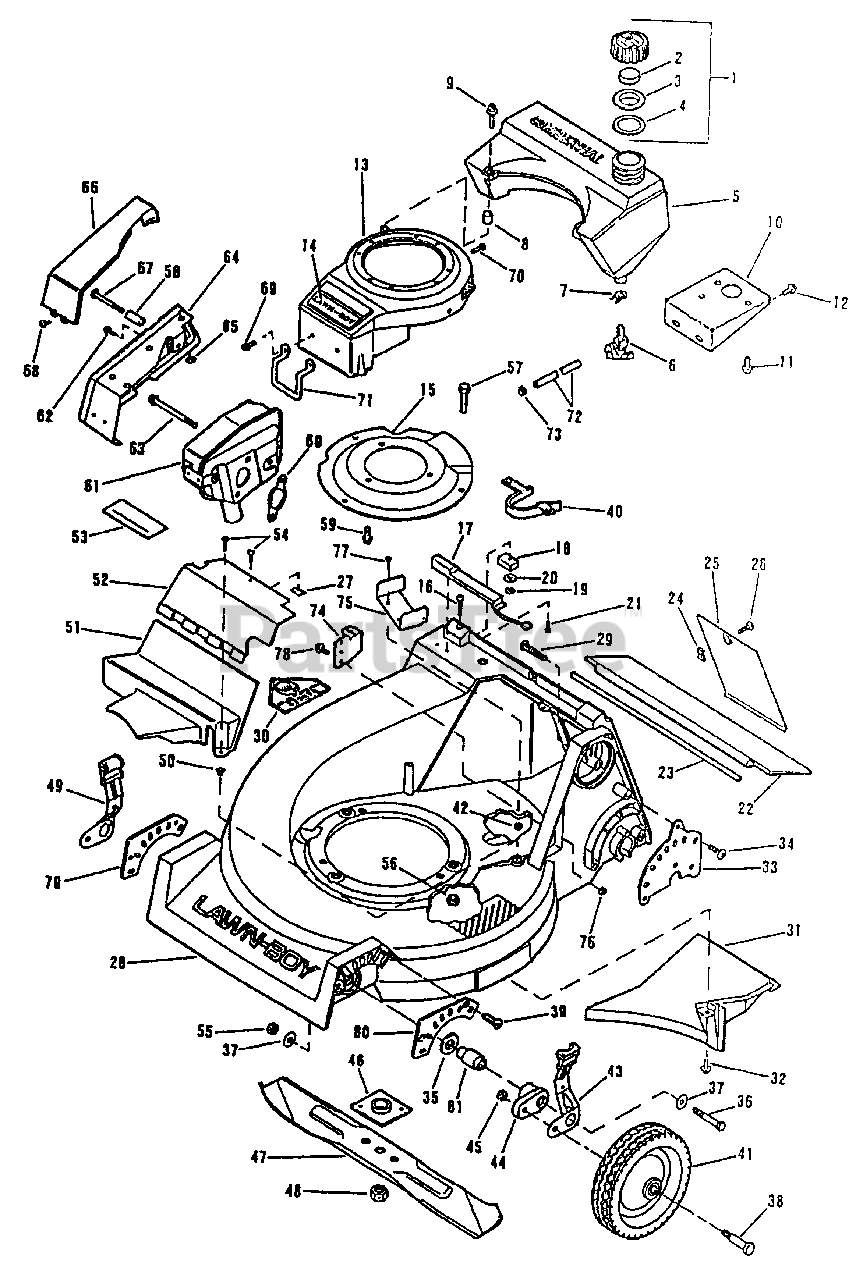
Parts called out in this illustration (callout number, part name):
1	Fuel Cap Assembly
2	Baffle
3	Cover
4	Gasket
5	Fuel Tank
6	Valve and Screen
7	Clamp
8	Spacer
9	Screw-SEMS Fuel Tank to Shroud
10	Fuel Tank Mounting Bracket
11	Screw-Fuel Tank to Bracket
12	Screw-Tank Bracket to Block
13	Shroud and Applique Assembly
14	Applique
15	Engine Munting Plate
16	Screw-Magnet to Housing
17	Bag Interlock Switch
18	Magnet
19	Nut-Magnet to Housing
20	Lockwasher-Magnet to Housing
21	Screw-Interlock Switch to Housing
22	Trailing Shield
23	Trailing Shield Pivot Rod
24	Speed Nut
25	Access Door
26	Screw-Access Door to Housing
27	Speed Nut
28	Housing Assembly
29	Handle Mounting Bolt
30	Decal-Blade Contact Warning
31	Battle-Chute Floor
32	Screw-Baffle to Housing
33	Height Adjust Plate
34	Screw-Plate to Housing
35	Flat Washer
36	Screw-Front Height Adjust Arm
37	Washer-Front Height Adjust Arm
38	Shoulder Bolt-Front Wheel
39	Flat Head Screw
40	Belt Guide-Engine
41	Wheel and Tire Assembly
42	Locknut-Belt Guide to Housing
43	Knob and Spring Assy-Front L.H.
44	Front Height Adjust Arm
45	Nut-Front Wheel Bolt (ZMRA)
46	Collar and Plate
47	21" Blade
48	Locknut-Blade
49	Knob and Spring Assy-Front R.H.
50	Grommet
51	Lower Drive Cover
52	Upper Drive Cover w/Decal
53	Decal-Warning
54	Screw-Drive Cover to Housing
55	Nut-Height Adjust Arm (ZMRB)
56	Locknut-Mting Plate to Housing
57	Screw-Mting Plate to Housing
58	Spacer-Muffler Guard
59	Screw-Mounting Plate to Engine
60	Exhaust Gasket
61	Muffler
62	Screw-Muffler Guard
63	Screw-Muffler
64	Muffler Guard Assembly
65	Pushnut
66	Muffler Cover
67	Screw-Muffler Guard
68	Screw-Muffler Guard
69	Hex Flange Head Screw
70	Screw-Shroud to Engine
71	Spark Plug Guard
72	Fuel Line
73	Clamp-Fuel Line to Carburetor
74	Cable Anchor
75	Belt Guide-Housing
76	Locknut-Cable Anchor to Housing
77	Screw-Belt Guide to Housing
78	Screw-Cable Bracket to Housing
79	Front Height Adjusting Plate-R.H.
80	Front Height Adjusting Plate-L.H.
81	Front Height Adjust Bushing
